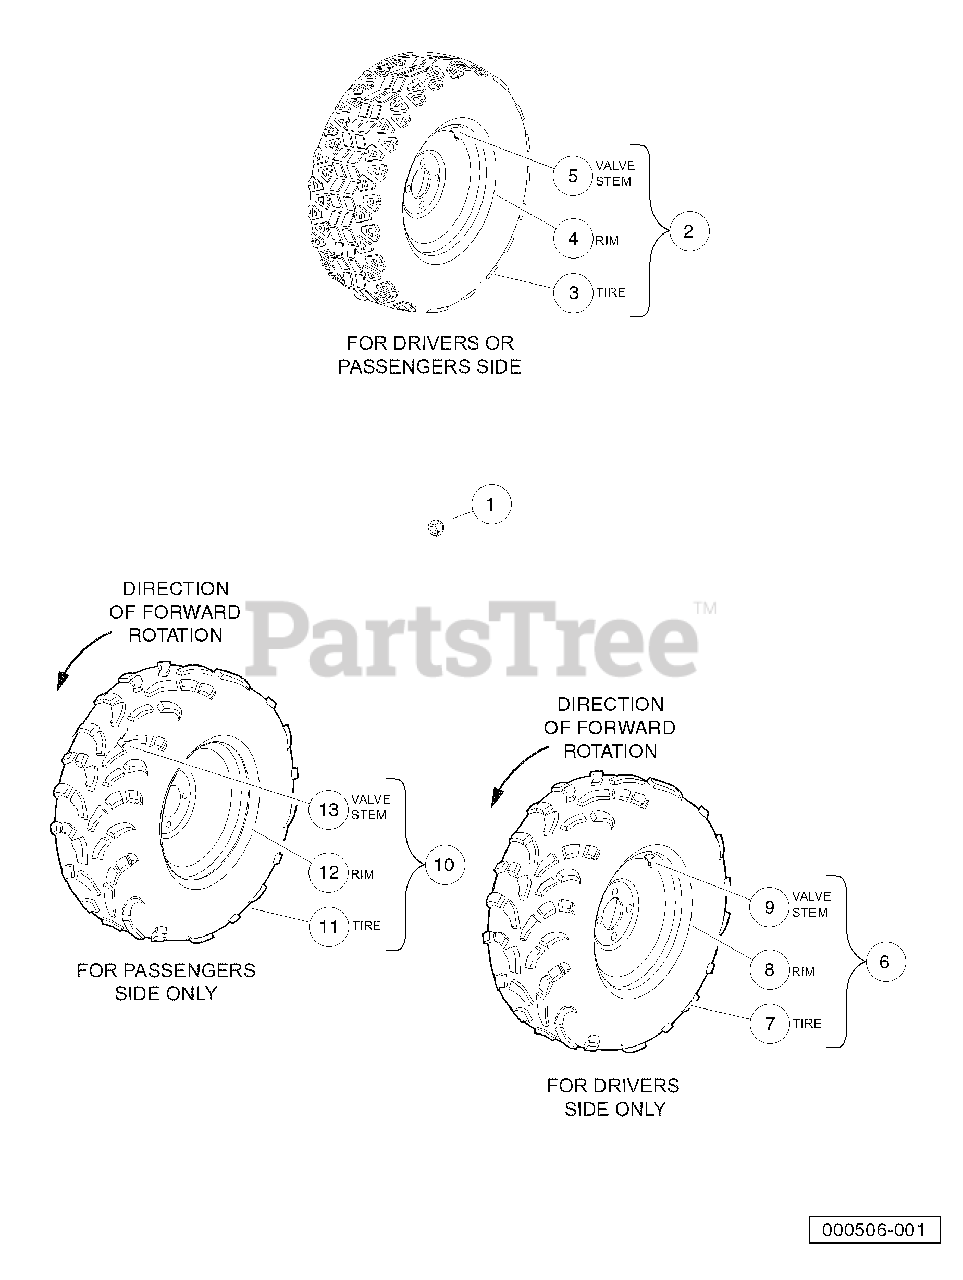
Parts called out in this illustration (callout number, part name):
1	Nut, Lug, 1/2-20 SAE J2283
2	Black Tire Asm HDAT 10.5 In
3	Heavy Duty All Terrain Tire, 25"
4	Wheel, All trail, 10 Win, Black
5	Valve Stem
6	Black Tire Asm Mud 11.0 In Left-Hand
7	Mud Tire, 25"
8	Wheel, All trail, 10 Win, Black
9	Valve Stem
10	Black Tire Asm Mud 11.0 In Right-Hand
11	Mud Tire, 25
12	Wheel, All trail, 10 Win, Black
13	Valve Stem
